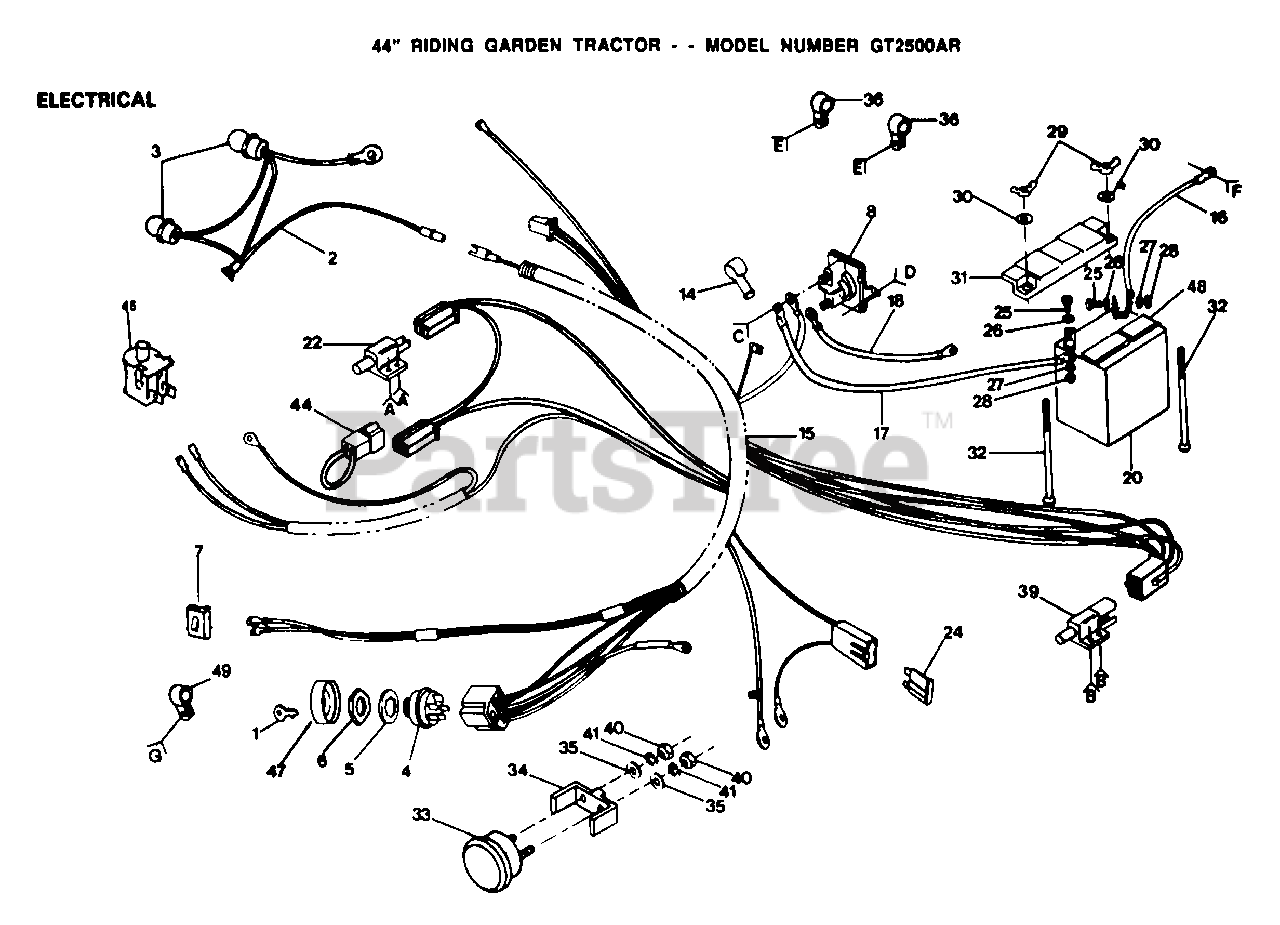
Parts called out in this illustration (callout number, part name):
2	HARNESS T
5	WASHER T
7	SWITCH LT
16	"CABLE T, BATTERY"
17	CABLE LT
18	CABLE T
22	SWITCH-INTER. GT
24	FUSE HYT
25	BOLT LT
26	WASHER
27	LOCKWASHER
30	LOCKWASHER GT
32	BOLT
33	AMMETER T
35	WASHER
36	CLIPT
39	SWITCH INTERLOCKT
45	SWITCH SEAT
46	LOCKWASHER
48	"CAP,BATTERY "
49	CLIPT
